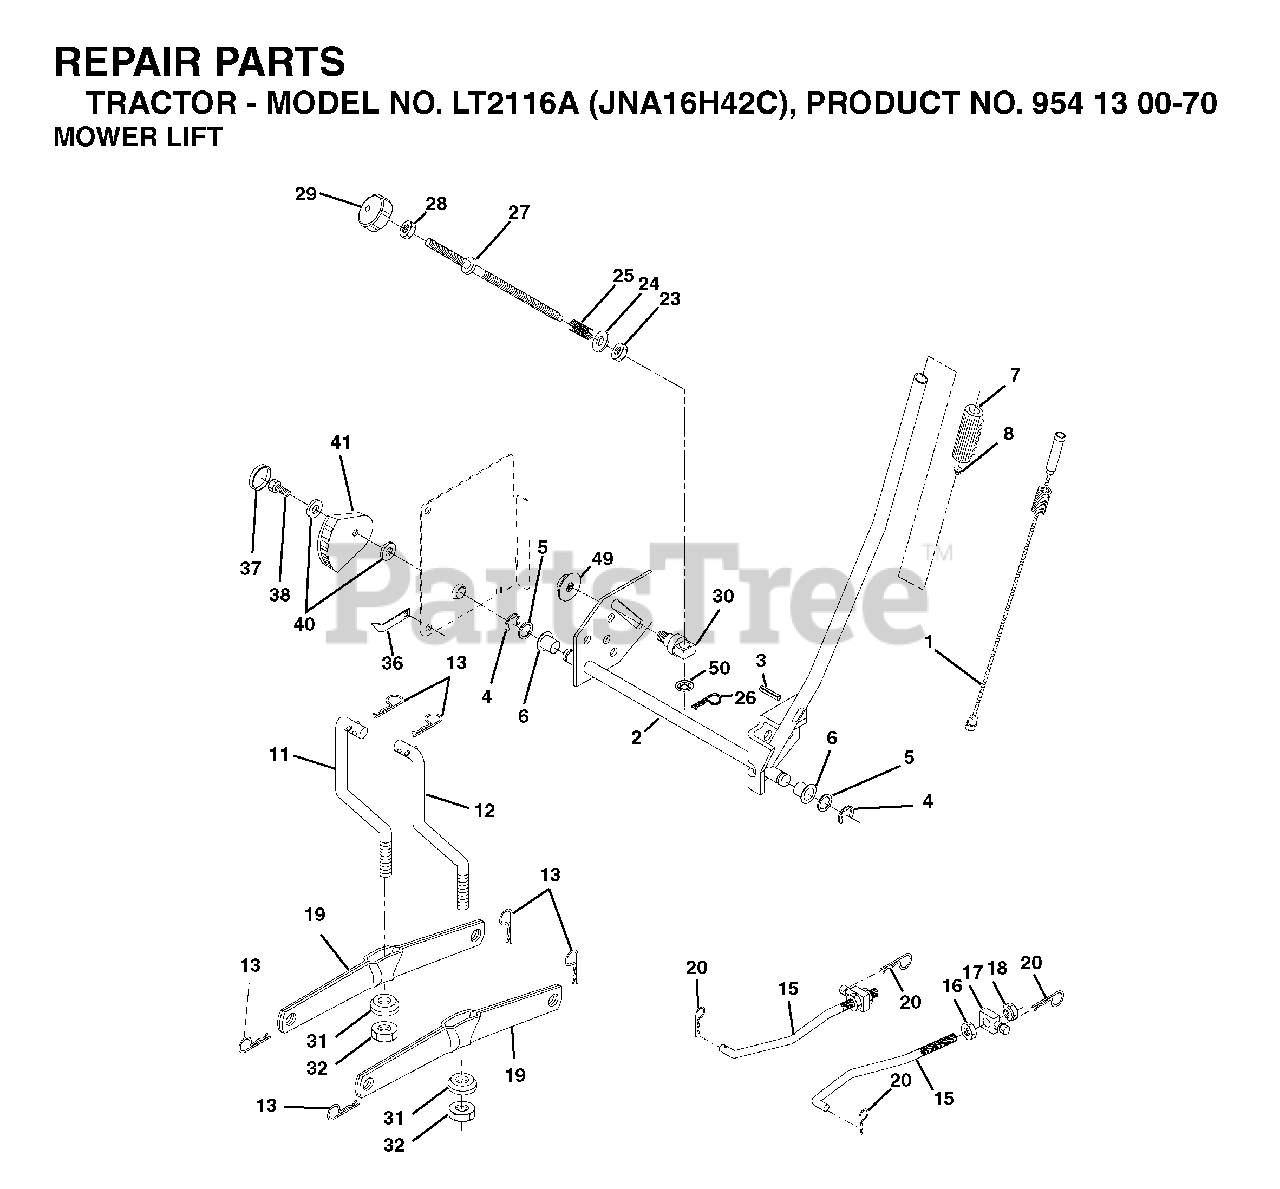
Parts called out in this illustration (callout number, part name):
1	WIRE ASM INNER W/ PLUNGER LT
2	SHAFT ASM R HANDLE
3	PIN GROOVE
4	RETAINING RING LT
6	BEARING.NYLON
7	GRIP HANDLE
8	PLUNGER BUT KIT
11	LINK LIFT LH
12	LINK LIFT RH
13	RETAINER-SPRNG RB
15	LINK.SUSPENSION.FRONT
16	NUT
18	NUT
19	ARM.REAR.SUSPENSION
20	SPRING RETAINER
25	SPRING**
26	RETAINER CLIP
27	ROD ADJ LIFT
28	NUT
29	KNOB INF 3/8-16
31	BEARING.PIVOT.LIFT
32	NUT CROWNLOCK 3/8-24
36	POINTER, HEIGHT INDICATOR
37	PLUG,HOLE
38	SCREW 5/16-18X1
41	IND. HEIGHT STLT
49	NUT
50	NUT PUSH M
